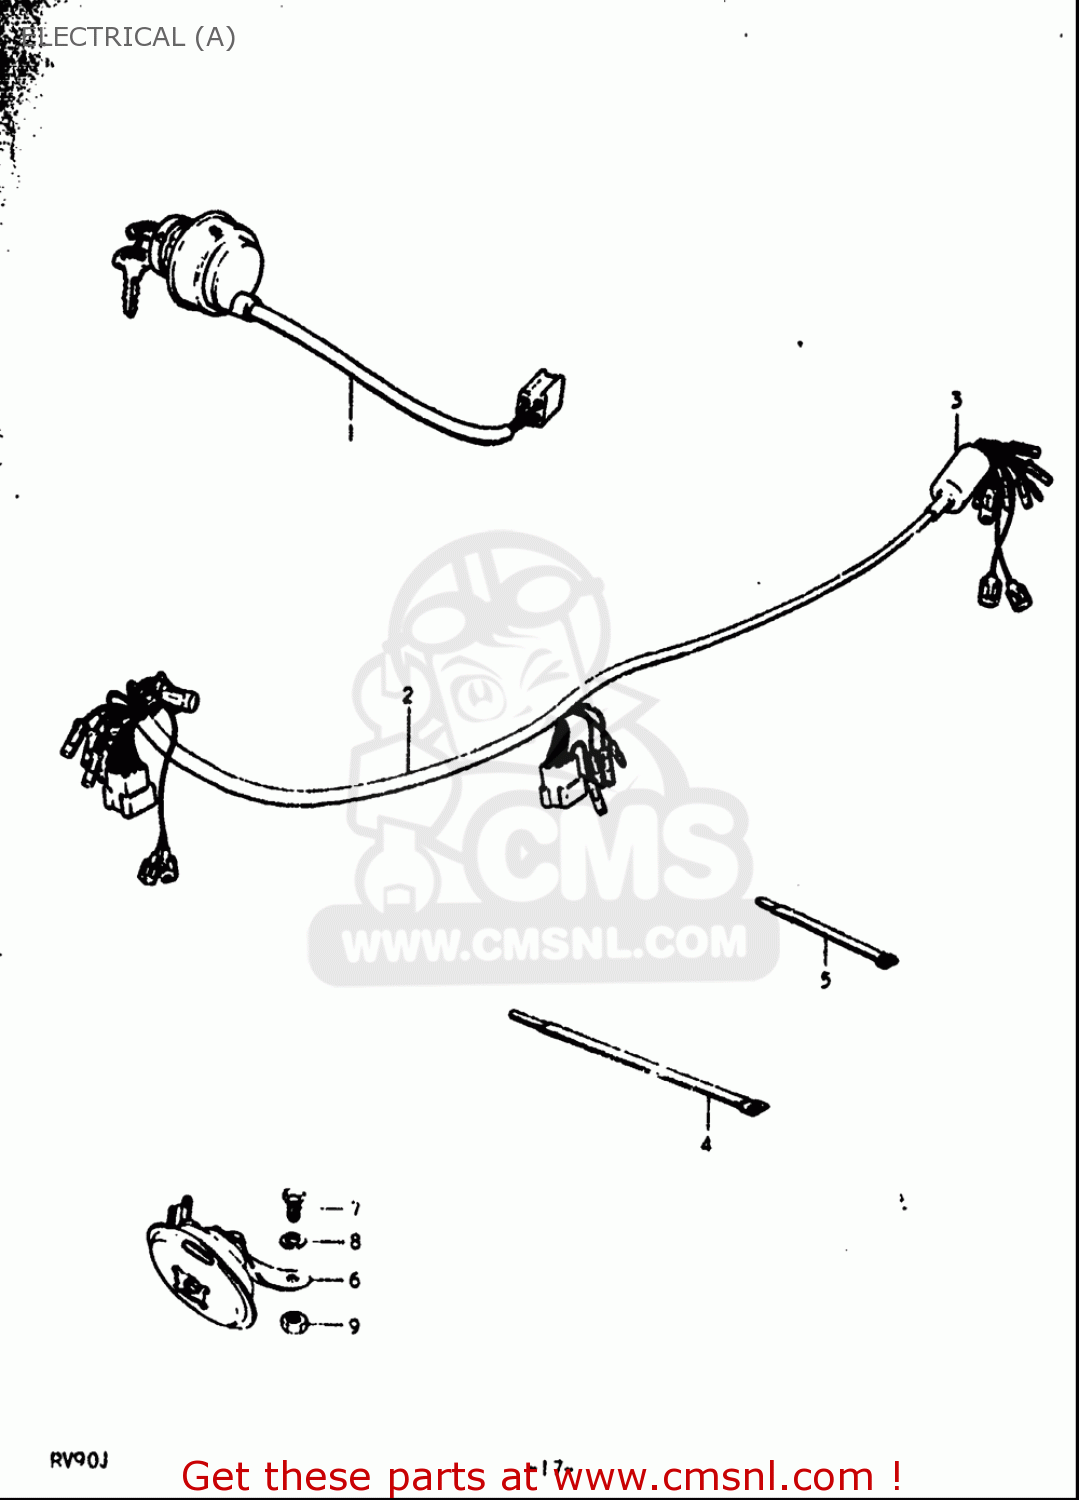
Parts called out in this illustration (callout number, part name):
1	SWITCH ASSY,IGNITION
3	BOOT,WIRING HARNESS
4	CLAMP(L:250)
5	CLAMP
7	BOLT(6X8)
8	WASHER,LOCK
9	NUT
